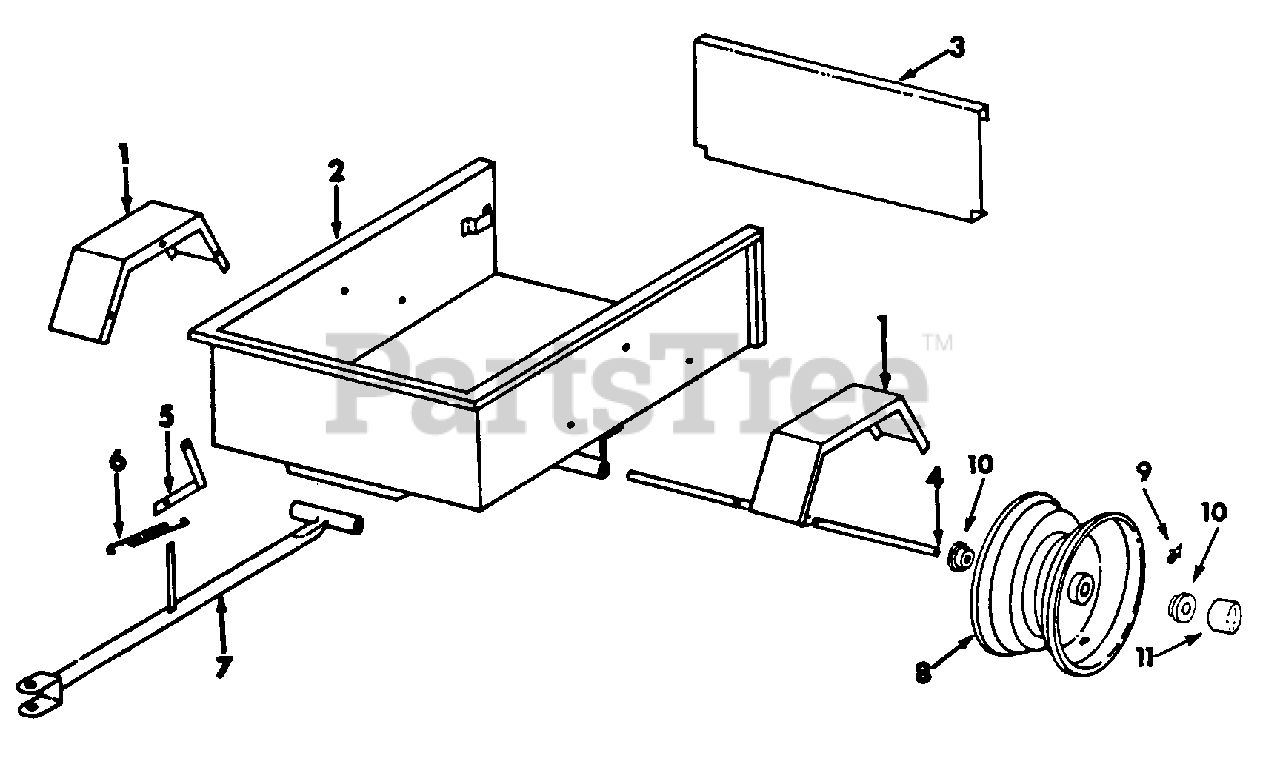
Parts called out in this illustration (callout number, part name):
2	Body, Trailer
6	Spring, Latch Return
8	Wheel Assy
9	Fitting, 1/4-28 Str Lub
10	Bearing
